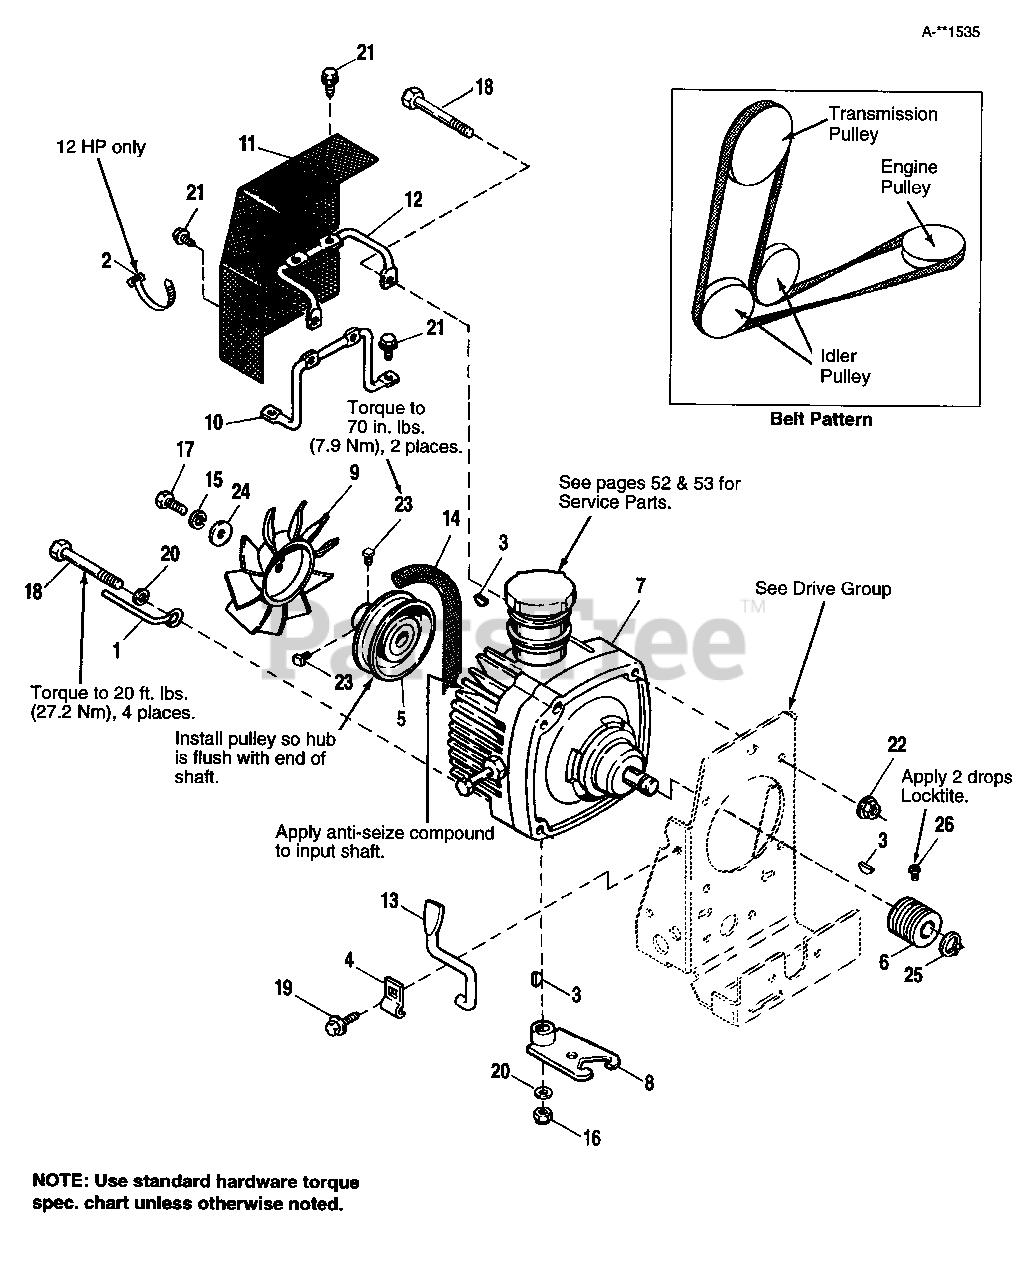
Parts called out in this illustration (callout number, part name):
3	KEY, Woodruff
4	CLIP, Tow Latch
5	PULLEY, Transmission
6	PULLEY, Drive
7	TRANSMISSION-Hydro Pump (See pages 52 & 53 for service parts)
8	CONTROL ARM ASSY.
10	MOUNTING BRACKET, Fan Guard
12	MOUNTING BRACKET, Fan Guard
13	ROD, Tow Latch
14	BELT, Drive
15	LOCKWASHER,1/4
16	NUT, Hex, ESNA Lock, 5/16-18
17	CAPSCREW, Hex, 1/4-20 x 1/2
18	CAPSCREW, Hex, 3/8-16 x 3
19	SCREW, Taptite, 5/16-18 x 1/2
20	WASHER, 5/16
21	SCREW, Hex, Taptite, 1/4-20 x 1/2
22	NUT, Hex, Whizlock, 3/8-16
23	SETSCREW, Sq. Hd., Cup Pt., 1/4-28 x 1/2
24	WASHER, 1/4 x 1-1/4
25	RING, Retaining
26	SETSCREW, 1/4-20 x 3/8
